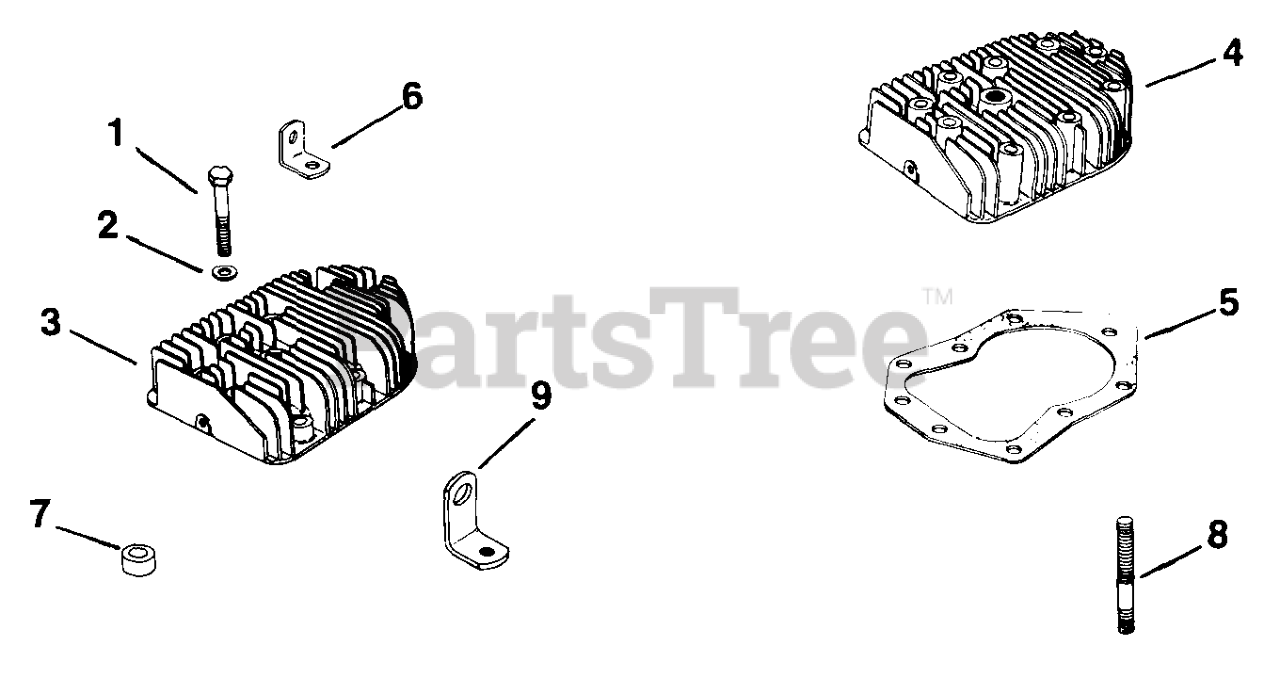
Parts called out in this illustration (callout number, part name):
1	SCREW, MACH 3/8-16X1-1/2" USE 25 086 115-S
1	SCREW - DISCONTINUED
2	WASHER, FLAT 13/32"
4	HEAD - DISCONTINUED
5	GASKET, HEAD
6	STRAP, LIFTING
